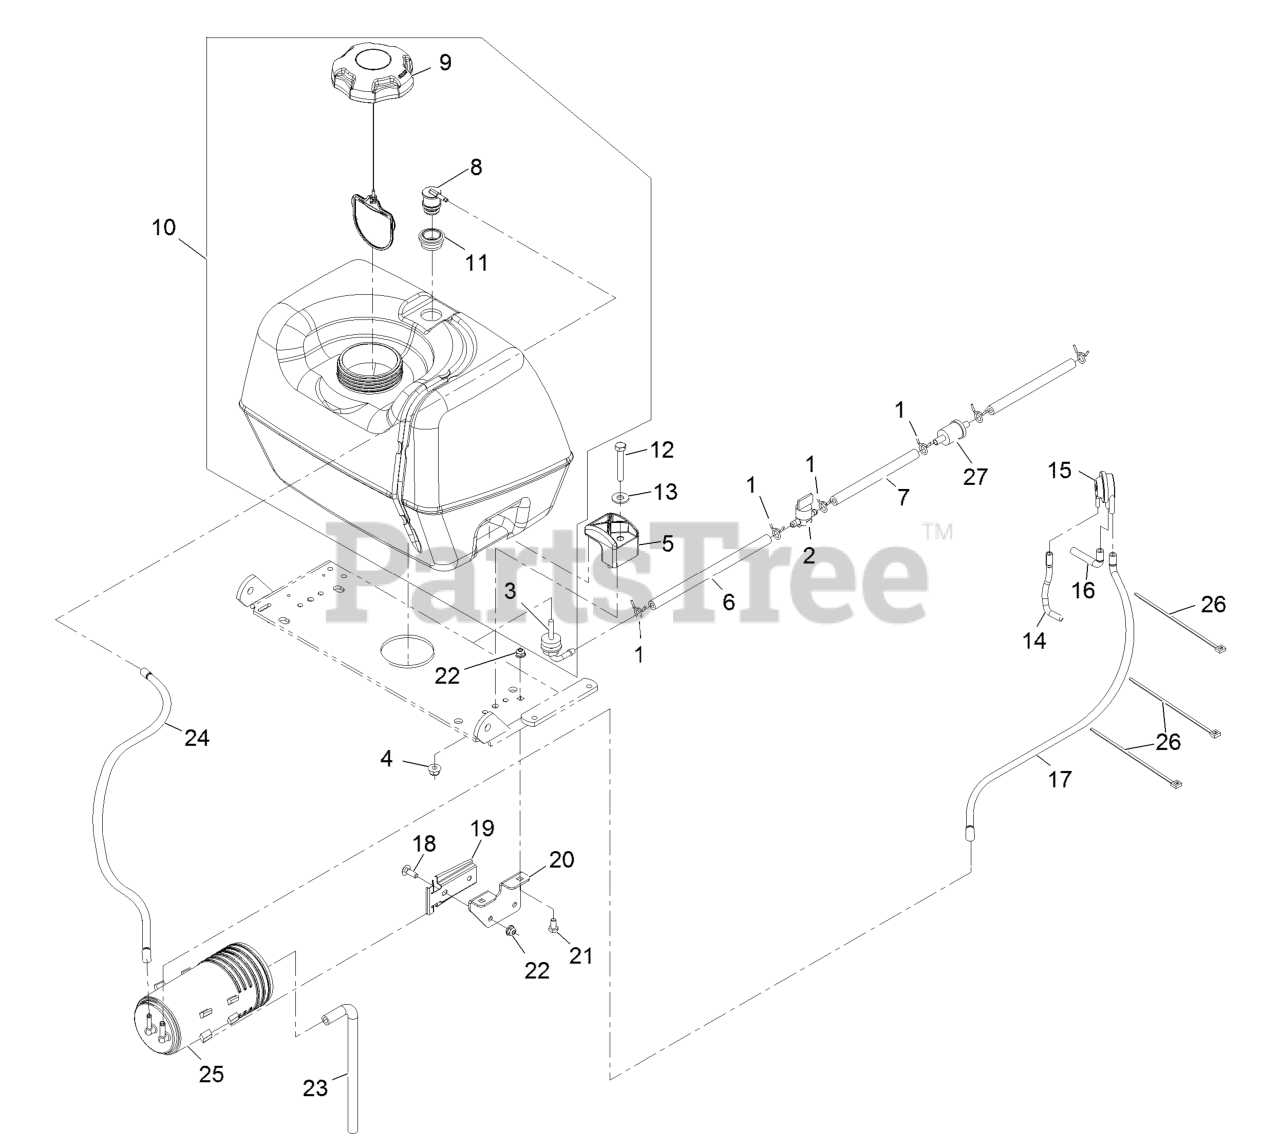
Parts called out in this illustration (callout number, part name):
1	CLAMP-HOSE
2	VALVE-FUEL
3	FITTING-FUEL, BULKHEAD
4	NUT-HF, NI
6	HOSE-FUEL
7	HOSE-FUEL
8	VALVE-VENT, FUEL
10	ASM, FUEL TANK
11	GROMMET
12	SCREW-HH
13	WASHER-FLAT
14	HOSE-VENT, FORMED
15	VALVE-CONTROL, VACUUM
16	HOSE-VENT, FORMED
17	HOSE-VENT, FORMED
18	SCREW-HH
19	BRACKET-CANISTER, CARBON
20	BRACKET-CANISTER, CARBON
21	BOLT-CARR
23	HOSE-VENT, CANISTER
24	HOSE-VENT
25	CANISTER-CARBON, 800CC
26	TIE-PLASTIC
27	Pn 41019-1055 Filter W/6in Fuel Line
